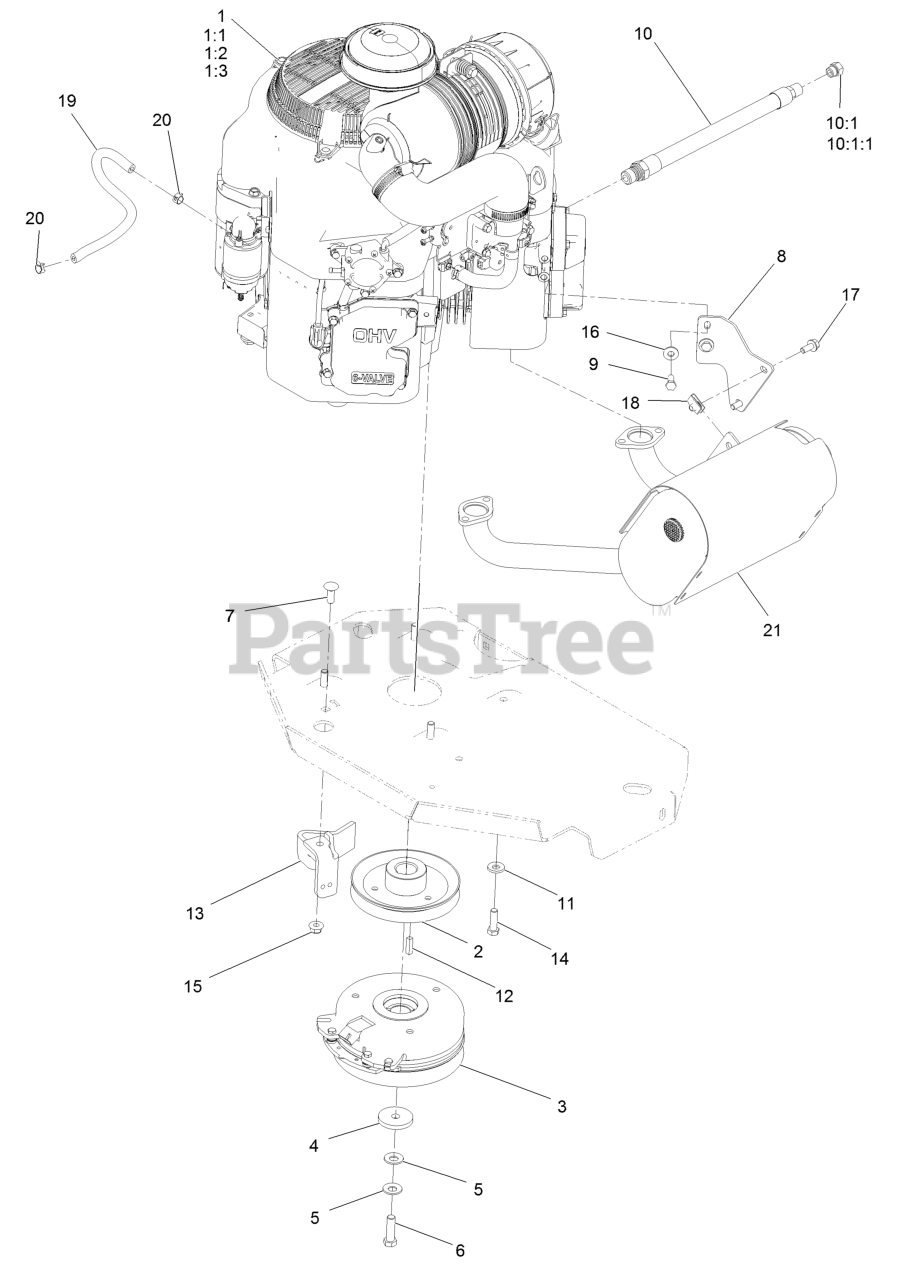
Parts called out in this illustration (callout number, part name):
1:1	Kawasaki 49065-7007 Engine Oil Filter
1:2	Kawasaki 11013-7044 Engine Air Filter
1:3	Kawasaki 11013-7045 Safety Filter
2	SHEAVE
3	CLUTCH KIT
4	WASHER-CLUTCH
5	WASHER-SPRING
6	SCREW-HH 7/16-20 X 1 1/2 W/LOCTITE
7	SCREW-CARR
8	BRACKET-MUFFLER
9	SCREW-HH
10	ENGINE OIL DRAIN HOSE ASM
10:1	PLUG-HH
10:1:1	O-RING
11	WASHER-BELLEVILLE
13	CLUTCH-ANCHOR
14	SCREW-HH
15	NUT-HF, NI
16	WASHER-SPRING
17	SCREW-HHF
19	HOSE-FUEL
20	CLAMP-HOSE
21	MUFFLER
